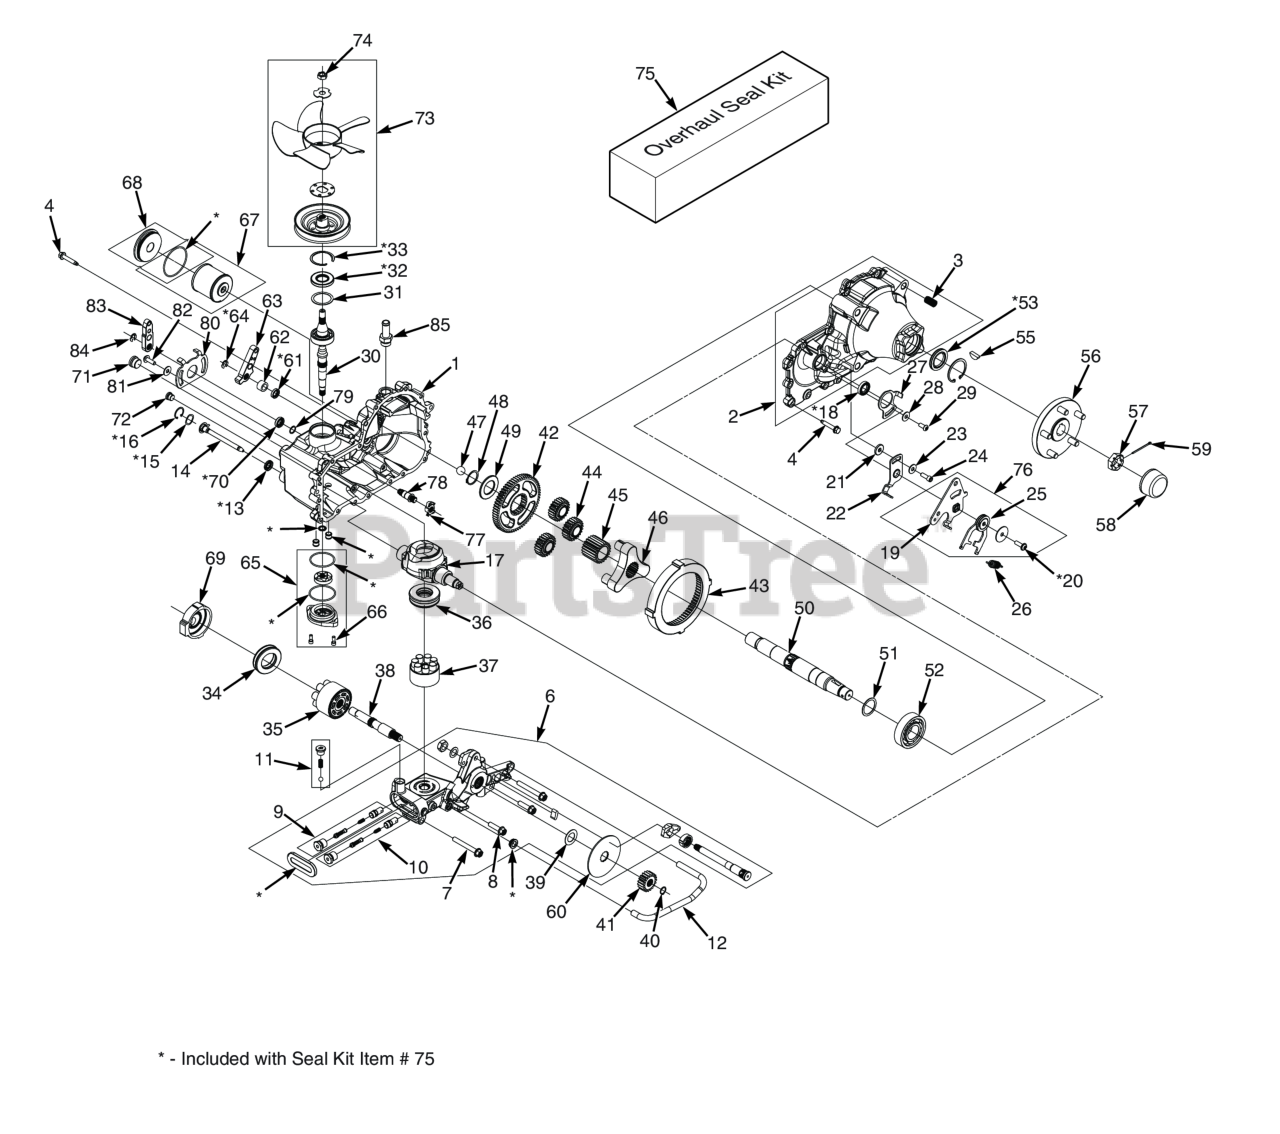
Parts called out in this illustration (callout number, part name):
1	Kit, Housing Main, LH
2	Kit, Housing Side, LH
3	Insert, 1/2-13 x 1-1/2" UNC
4	Screw, Hex Flange 5/16-18 x 1-1/2"
5	Tube, Sealant
6	Kit, Center Section, LH
7	Bolt, Hex Flange 3/8-16 x 3"
8	Screw, Hex Flange Head 3/8-16 x 1-1/2"
9	Kit, Shock Valve
10	Kit, Shock Valve
11	Kit, Charge Relief
12	Tube, Filter, LH
13	Seal, Lip 12x 24 x 5 TC
14	Kit, Bypass Actuator
15	Spring, Wave
16	Ring, Retaining, HO-100
17	Swash Plate, 16cc. Machined
18	Seal, Lip 22 x 32 x 7
19	Arm, Control, LH
20	Bolt, Hex Head Cap Screw 5/16-24 x 1" Patch
21	Spacer, .320 x 1.005 x .179
22	Arm, Neutral (Left Side)
23	Washer, 7/16 x 7/8 OD x .06 HT
24	Bolt, Hex Head Cap Screw 5/16-24 x 1" Patch
25	Assembly, RTN Uni-Directional (CCW) LH
26	Spring, Extension, RTN - 44lbs
27	Plate, Stop, LH
28	Washer, 7/16 x 7/8 OD x .06 HT
29	HBHCS, 5/16-18 x 3/4"
30	Kit, Input Shaft
31	Spacer
32	Seal, Lip 25 x 52 x 7 TC
33	Ring, Retaining Internal
34	Bearing, Thrust 42 x 68 x 16
35	Kit, Cylinder Block - 21cc.
36	Bearing, Thrust 35 x 70 x 22
37	Kit, Cylinder Block - 16cc.
38	Shaft, Motor
39	Washer, .89 x 1.50 x .04
40	Ring, Retaining .625
41	Gear, 19T
42	Gear, 65T
43	Gear, Ring 68T
44	Gear, Planet 23T
45	Gear, Sun 22T
46	Carrier
47	Ball, Thrust .75
48	Ring, Retaining 1-1/4"
49	Spacer, Thrust, Axle
50	Shaft, Axle
51	Washer, 1.40 x 1.75 x .05
52	Bearing, Ball 35 x 80 x 21
53	Seal, Lip 1.375 x 2.062 x .250
54	R i n g , Retaining 2.06 Internal
55	Key, Shaft, Axle
56	Kit, Hub, 5-Bolt
57	Nut, Hex 1-20 Slotted
58	Cap, Axle
59	Pin, Cotter 9/64 x 2"
60	Rotor, Brake
61	Seal, .56 x .88 x .19
62	Spacer, .57 x .86 x .53
63	Handle, Actuating
64	Ring, Retaining External .375"
65	Kit, Charge Cover
66	Screw, 1/4-20 x .625
67	Kit, Filter
68	Kit, Filter Plug
69	Plate, Motor Swash
70	Lip Seal (15 x 24 x 7)
71	Plug, 7/8-14
72	Straight Thread Plug
73	Kit, Fan / Pulley
74	Fan Nut (order through Hydro-Gear)
75	Seal Kit
76	Kit, RTN Bi-Directional LH
77	Cam, 2-Speed
78	Shaft, 2-Speed, Bevel
79	Ring, Retaining External .59"
80	Arm, Lock Down 2-Speed
81	Washer, 7/16 x 7/8 OD x .06 HT
82	HBHCS, 5/16-18 x 3/4"
83	Handle, Actuating
84	Ring, Retaining External .375"
85	Fitting, 7/8-14 SAE, .625 Beaded
